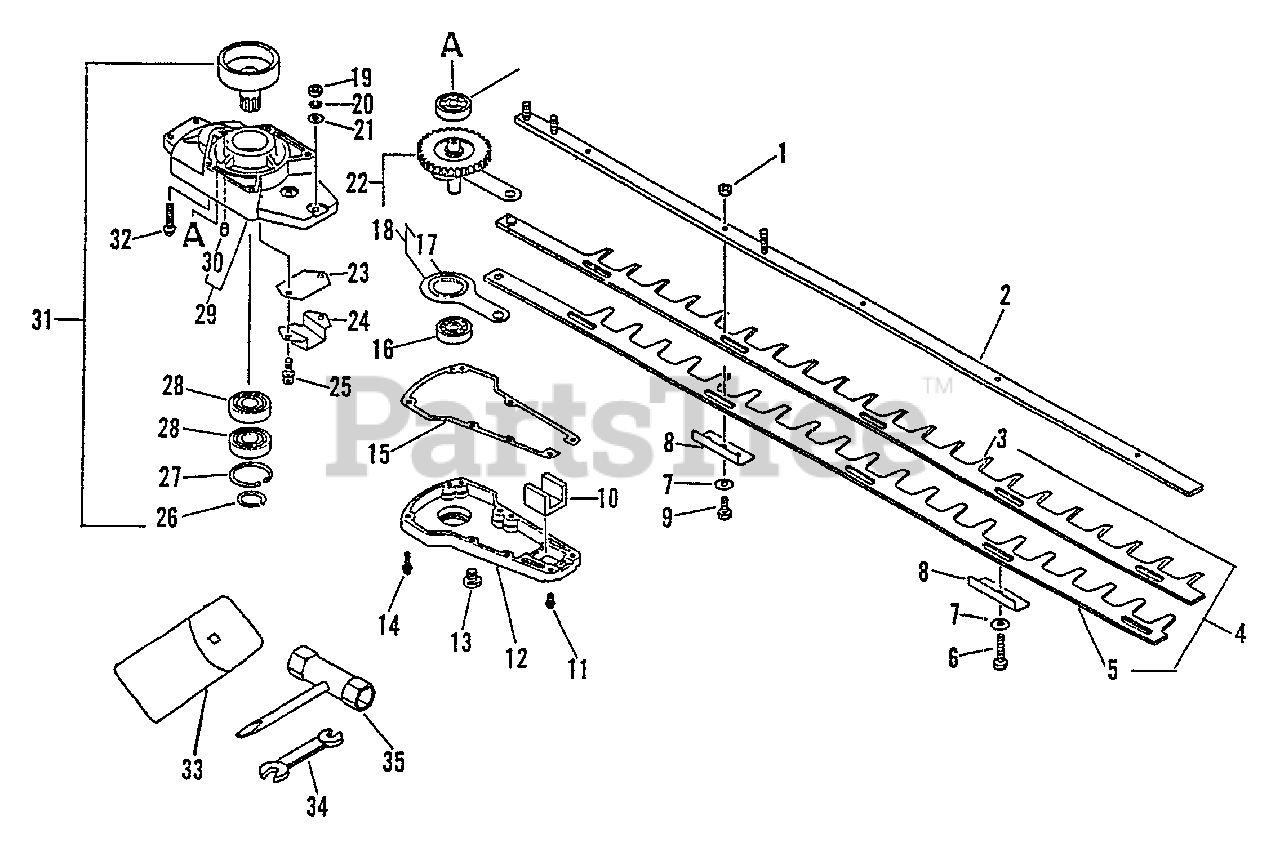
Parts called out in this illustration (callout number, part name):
2	SUPPORT, BLADE
3	BLADE - UPPER
4	TRIMMER BLADE SET
5	BLADE - LOWER
8	INSULATOR
10	SEAL, FELT
11	SCREW - 4X14
12	LID, GEAR CASE
13	BOLT - 8X8
14	SCREW - 4X22
15	GASKET, GEAR CASE
16	BEARING, BALL - 6200
17	BEARING, NEEDLE
18	CONNECTING ROD ASSY
19	LOCKNUT - 6
20	LOCKWASHER - 6
21	WASHER - 6
22	GEAR ASSY
23	PLATE, GUIDE
24	GUIDE
25	SCREW - 5X14
26	RING, RETAINING - 16
27	RING, RETAINING - 35
28	BEARING, BALL - 6003
29	CASE, GEAR
30	PIN - LOCATING
31	DRUM, CLUTCH
32	SCREW - 5X30
33	BAG, TOOL
34	SPANNER - 8X10mm
35	T-WRENCH - 14X19mm
